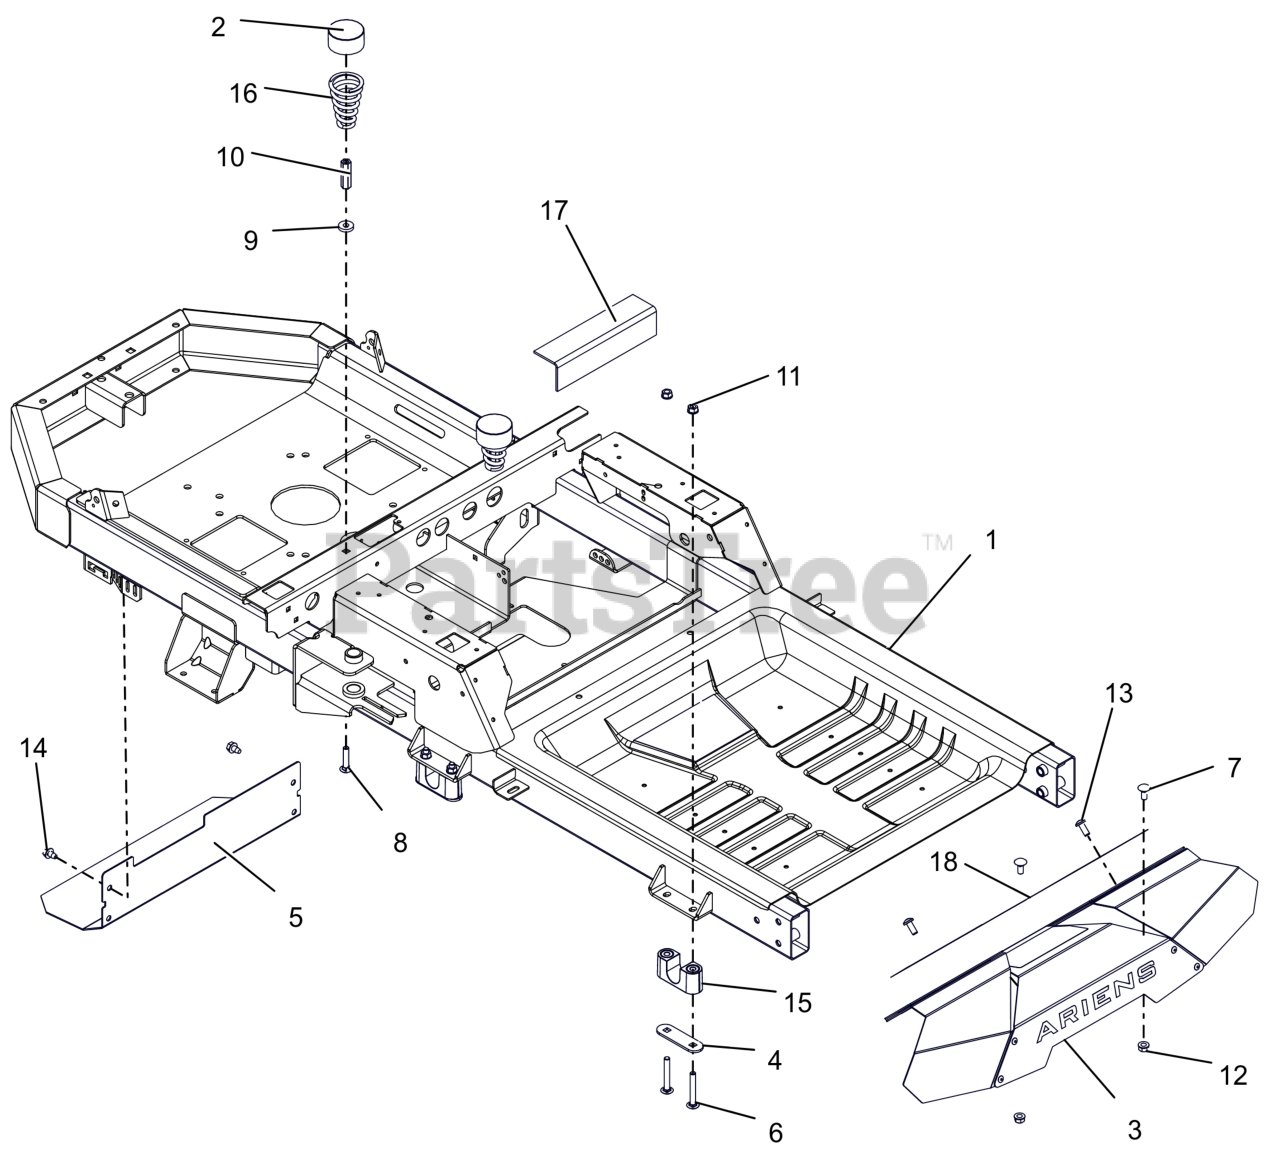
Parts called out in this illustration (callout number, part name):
1	KIT, IKON-X/XL FRAME (2016)
2	HUB CAP
3	KIT, IKON FOOT REST W/DECAL
4	PLATE, BEARING SUPPORT
5	HEAT, SHIELD
6	BLT, RHSSN.31-18X2.25 G5 ZCC
7	BLT,RHSN .31-18X.75 G5 ZCC
8	BLT,RHSN .31-18X1.50 G5 ZCC
9	WSHR, FLT .328X.870X.179 ZCC
10	NUT, COUPLING .31-18X1.75 ZCC
11	NUT,LK-CTR-FLG .31-18 GF ZCC
12	NUT-LK-TOP-FLG .312-18 GF ZCC
13	SCR-RDHDSKTAP .31-18X.75 ZCC
14	SCR,TAP .312-18X.50 HWH TR ZCC
15	BSHG, DECK LIFT PIVOT
16	SPRING, SEAT
17	PAD, RUBBER-TANK
18	GRIP TAPE, FOOT PLATE
